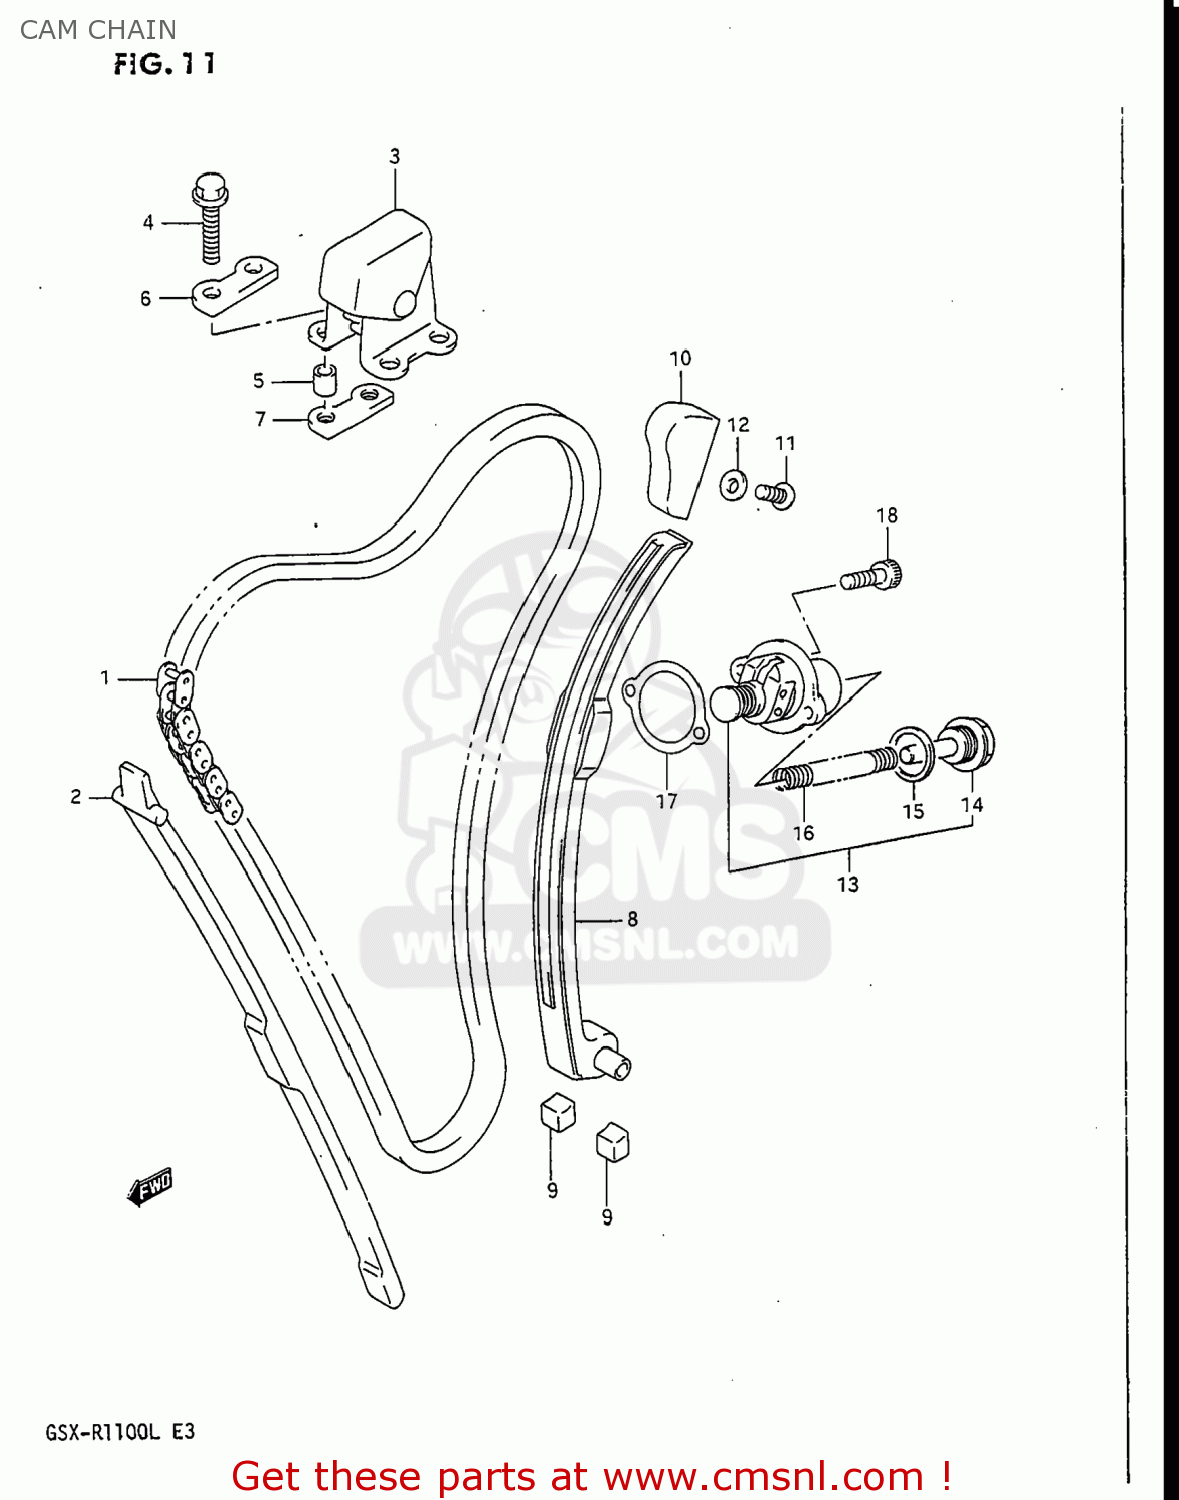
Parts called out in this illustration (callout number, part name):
1	CHAIN,CAMSHAFT DRIVE
2	GUIDE,CAM CHAIN NO.1
3	IDLER,CAM CHAIN
4	BOLT
5	SPACER (6,8X10X9.4)
6	CUSION,IDLER
7	CUSHION,IDLER
8	TENSIONER,CAM CHAIN
9	CUSHION,CAM CHAIN TENSIONER
10	GUIDE,CAM CHAIN NO.2
11	BOLT
12	GASKET(5.8X13X1.2) (NAS)
13	ADJUSTER ASSEMBLY,TENSIONER
14	PLUG
15	GASKET (NAS)
16	SPRING
17	GASKET,TENSIONER ADJUSTER (NAS)
18	BOLT
